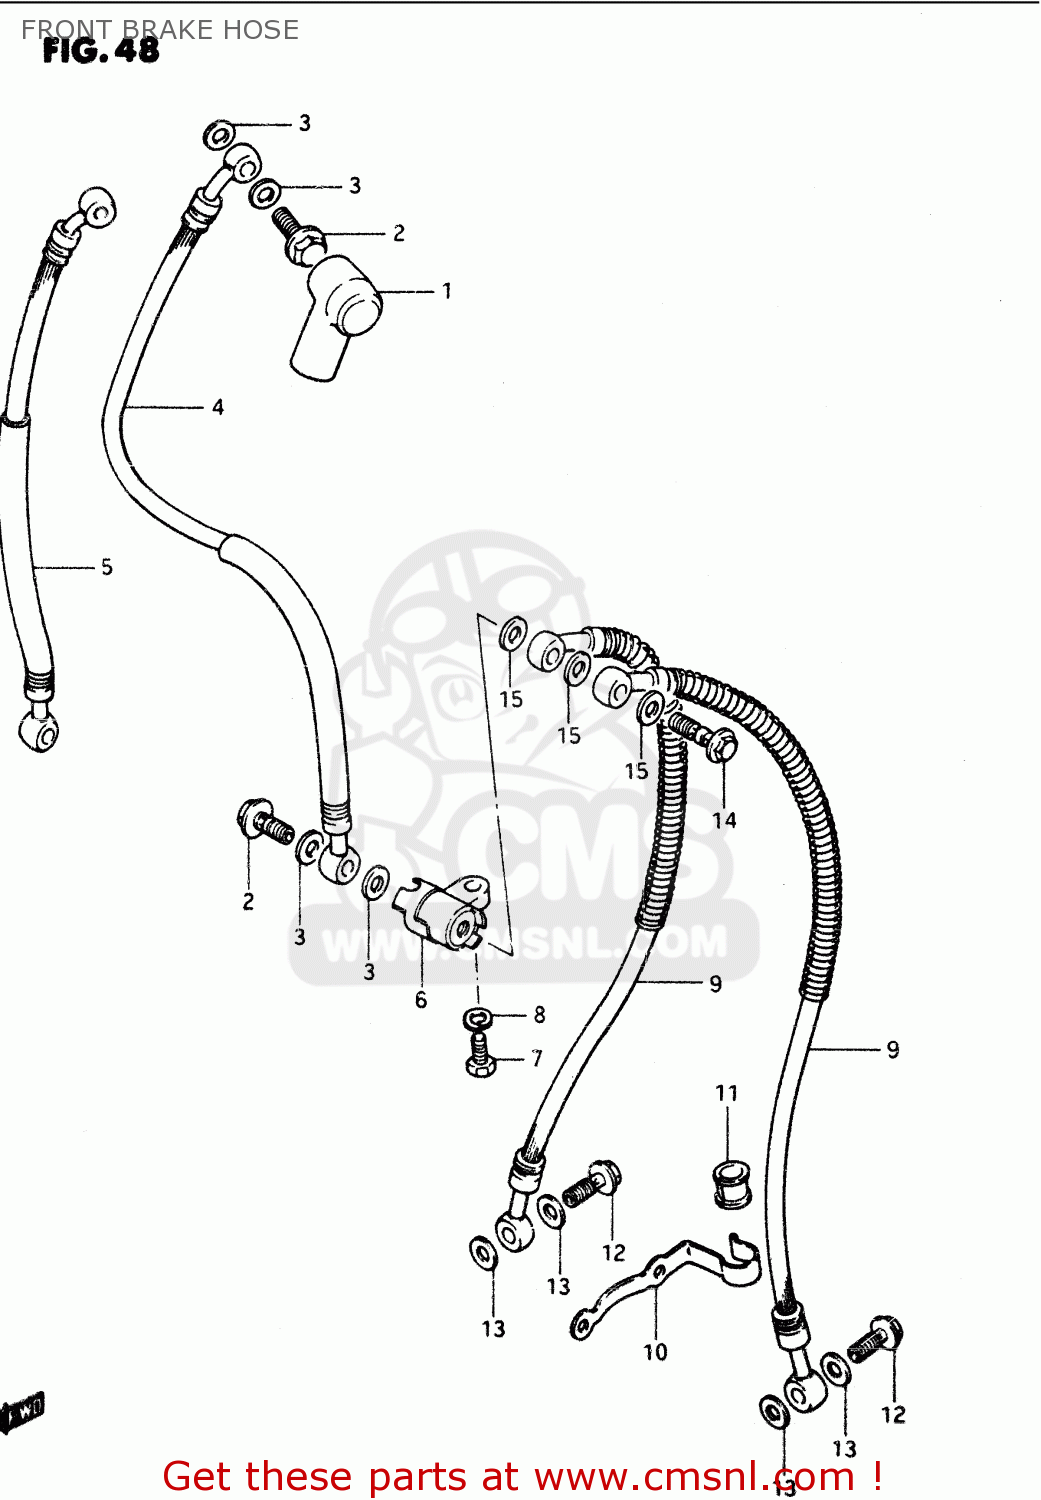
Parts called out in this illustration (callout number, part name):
1	BOOT,MASTER CYLINDER
2	BOLT UNION
3	WASHER(10X15X1.5)
4	HOSE,BRAKE NO.1
5	HOSE, BRAKE NO.1 (L:390)
6	JOINT,BRAKE HOSE
7	BOLT
8	WASHER,LOCK
9	HOSE,FRONT BRAKE
10	GUIDE,BRAKE HOSE NO.2
11	BUSH,BRAKE HOSE GUIDE,NO.2
12	BOLT UNION
13	WASHER(10X15X1.5)
14	BOLT UNION
15	WASHER(10X15X1.5)
